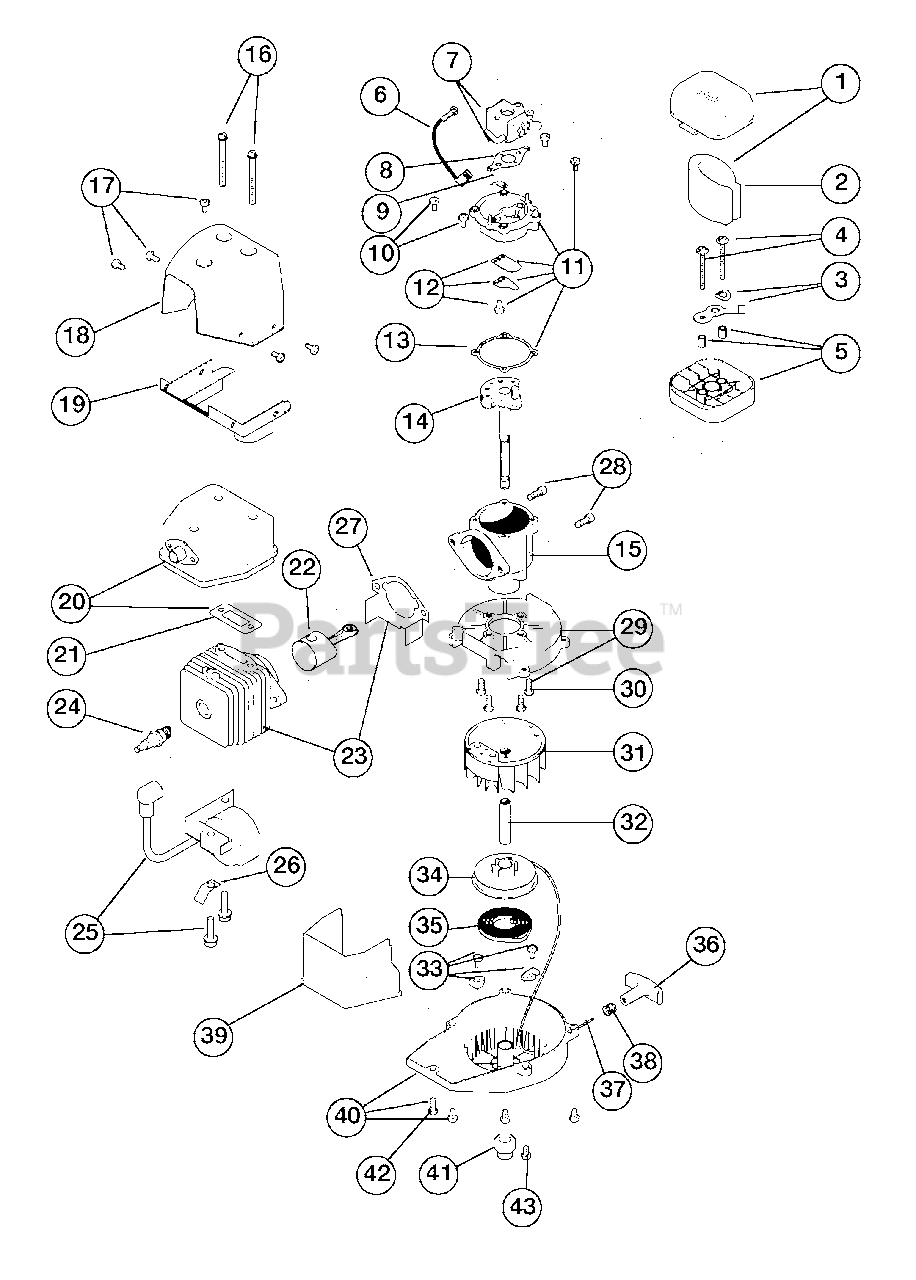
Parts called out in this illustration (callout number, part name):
1	Air Cleaner Cover Assembly
2	Air Cleaner Filter
3	Choke Lever Assembly
4	Mounting Bolt Assembly
5	Air Cleaner Base
6	Wire Lead
7	Carburetor Assembly
8	Carburetor Gasket (10 pack)
9	Ground Tab
10	Reed Plate Mounting Screw
11	Complete Reed Plate Assembly
12	Reed Assembly
13	Reed Plate Gasket
14	Crankshaft Assembly
15	Crankcase Service Assembly
16	Muffler Mounting Bolt
17	Mounting Screw Assembly
18	Upper Heat Shield
19	Lower Heat Shield
20	Muffler Assembly
21	Exhaust Gasket (10 pack)
22	Piston and Rod Assembly
23	Cylinder Assembly
24	Spark Plug
25	Module Assembly
26	Ground Tab
27	Cylinder Gasket
28	Cylinder Bolt
29	Shroud Assembly
30	Shroud Screw
31	Flywheel Assembly
33	Pulley Retainer Assembly
34	Recoil Pulley Assembly
35	Recoil Spring
36	Pull Handle
38	Rope Guide
39	Shroud Extension
40	Starter Housing Assembly
41	Crankshaft Extension
42	Shroud Extension Screw
43	Housing Screw
